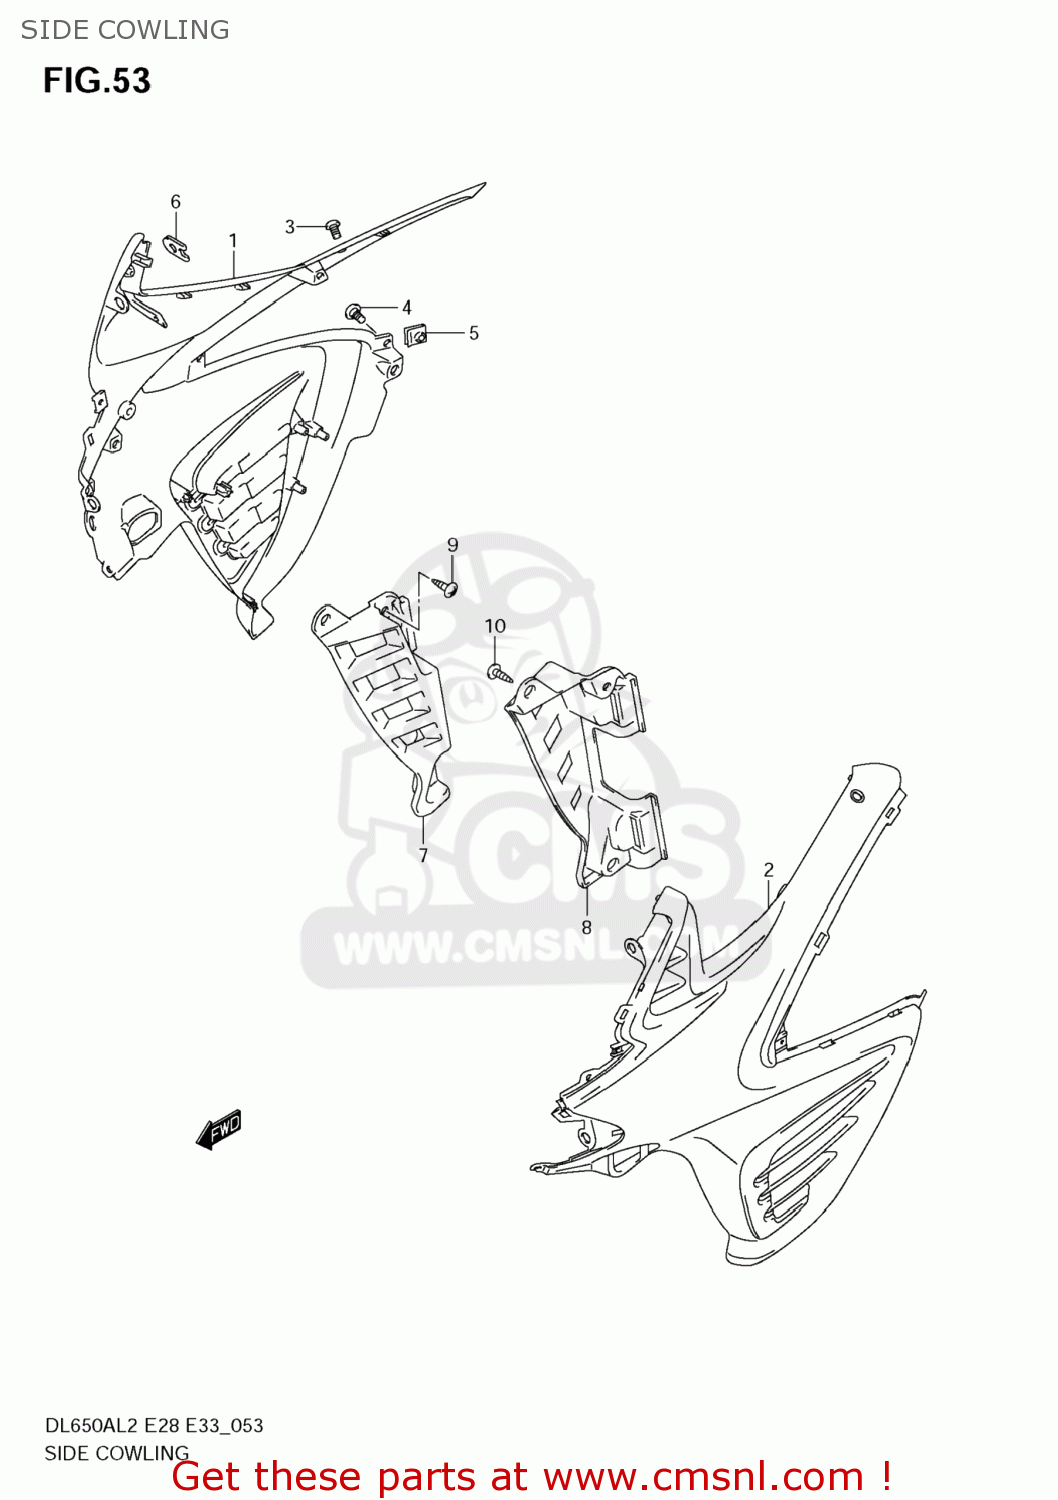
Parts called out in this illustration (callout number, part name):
1	COWLING,SIDE,R
2	COWLING,SIDE,L
3	SCREW(6X10)
4	SCREW(6X12)
5	NUT
6	NUT
7	COVER,COWLING INNER,R
8	COVER,COWLING INNER,L
9	SCREW
10	SCREW
